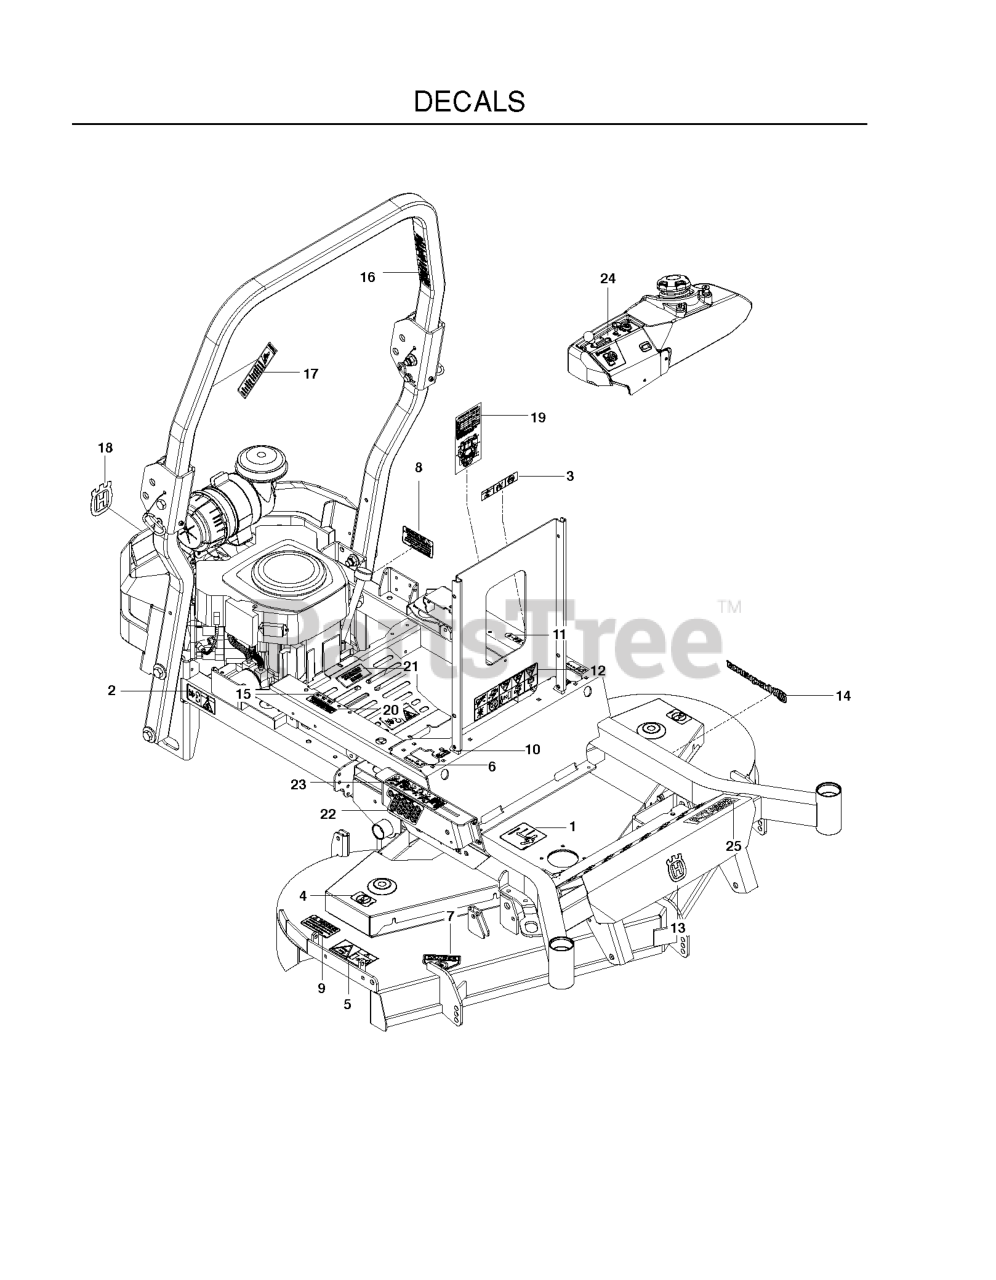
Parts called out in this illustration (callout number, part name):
1	DECAL, BELT ROUTING
2	DECAL, BELT DRIVE
3	EURO DECAL-BATTERY WARNIN6
4	DECAL, NO STEP
5	DECAL, EURO SEVERING
6	DECAL, MOTION CONTROL
7	DECAL, CPSC
8	DECAL, PROP. 65
9	DECAL, CAUTION
10	DECAL, F.S.T.
11	DECAL, PARK BRAKE
12	DECAL.ZTR.WARNING.SMARTIGNITIN
13	DECAL.AUGER.HUSQ.CROWN.SNOW
14	RP.DECAL.BADGE.170MM.TEXTLOGO
15	DECAL, FUSE
16	DECAL, ROPS
17	DECAL, ROPS, WARNING
18	DECAL, CROWN H, 110MM
19	DECAL, SERVICE
20	DECAL, WARNING SPARK ARRESTOR
21	HG_DECAL, ZT-3400
22	DECAL, HEIGHT
23	DECAL, RELEASE LEVER
24	DECAL, CONTROL, GAS
